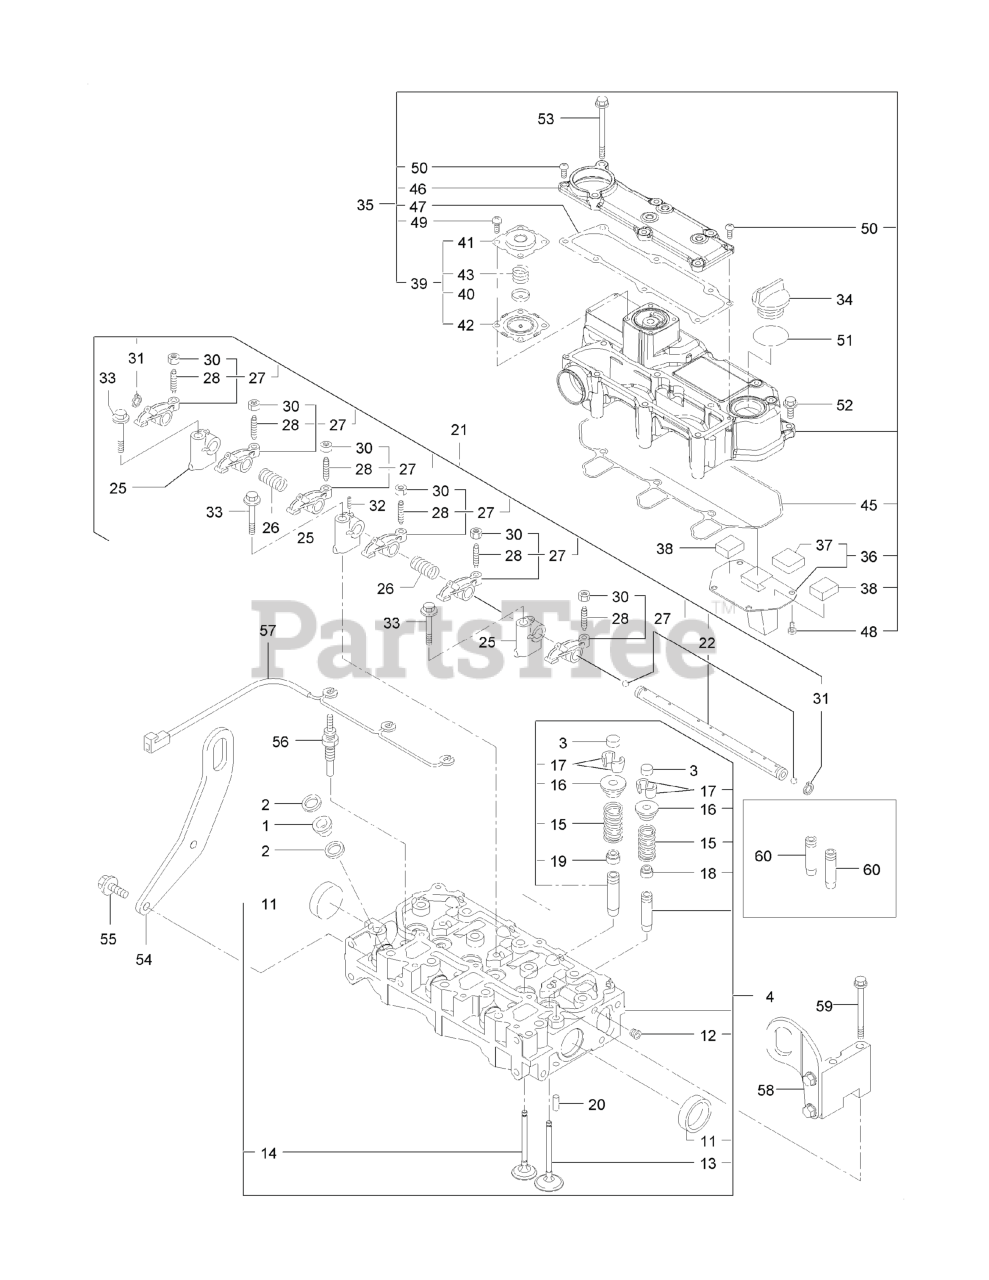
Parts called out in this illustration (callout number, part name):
1	PROTECTOR-NOZZLE
2	GASKET-NOZZLE
3	CAP-VALVE
4	Head ASM-Cylinder
11	PLUG-CUP
13	VALVE-SUCTION
14	VALVE, EXHAUST 3
15	SPRING-VALVE
16	RETAINER
18	SEAL-STEM, VALVE
19	SEAL-STEM, VALVE
20	PIN-SPRING
21	SUPPORT ASM-ROCKER
22	SHAFT ASM-ROCKER
25	SUPPORT-ROCKER ARM
26	SPRING-ROCKER
27	ARM ASM-ROCKER
28	SCREW-ADJUST, VALVE
34	COVER-FILLER
35	BONNET ASM
36	PLATE-BAFFLE
37	BAFFLE-BREATHER
38	BAFFLE-BREATHER
39	DIAPHRAGM ASM
40	PLATE-DIAPHRAGM
41	COVER-DIAPHRAGM
42	DIAPHRAGM
43	SPRING-DIAPHRAGM
45	GASKET-BONNET
46	COVER ASM-BONNET
54	LIFTER-ENGINE
56	PLUG-GLOW
57	CONNECTOR-GLOW PLUG
58	LIFTER ASM
